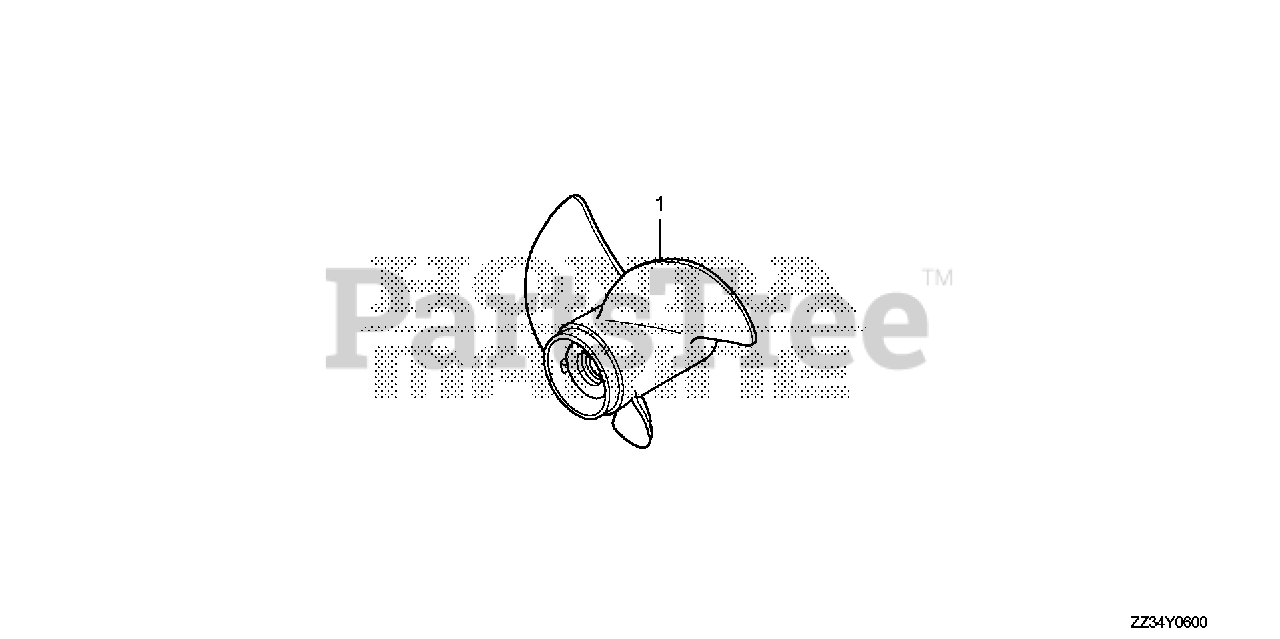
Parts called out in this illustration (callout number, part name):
1	PROPELLER, THREE-BLADE (14X11) *NH283* (AL) (STIN GRAY)
1	PROPELLER, THREE-BLADE (13-3/4X13) *NH283* (AL) (STIN GRAY)
1	PROPELLER, THREE-BLADE (13-1/4X17) *NH283* (AL) (STIN GRAY)
1	PROPELLER, THREE-BLADE (13X19) *NH283* (AL) (STIN GRAY)
1	PROPELLER, THREE-BLADE (13-1/2X15) *NH283* (AL) (STIN GRAY)
1	PROPELLER, THREE-BLADE (13-1/5X19) *NH283* (STIN GRAY)
1	PROPELLER, THREE-BLADE (14X9) *NH283* (STIN GRAY)
